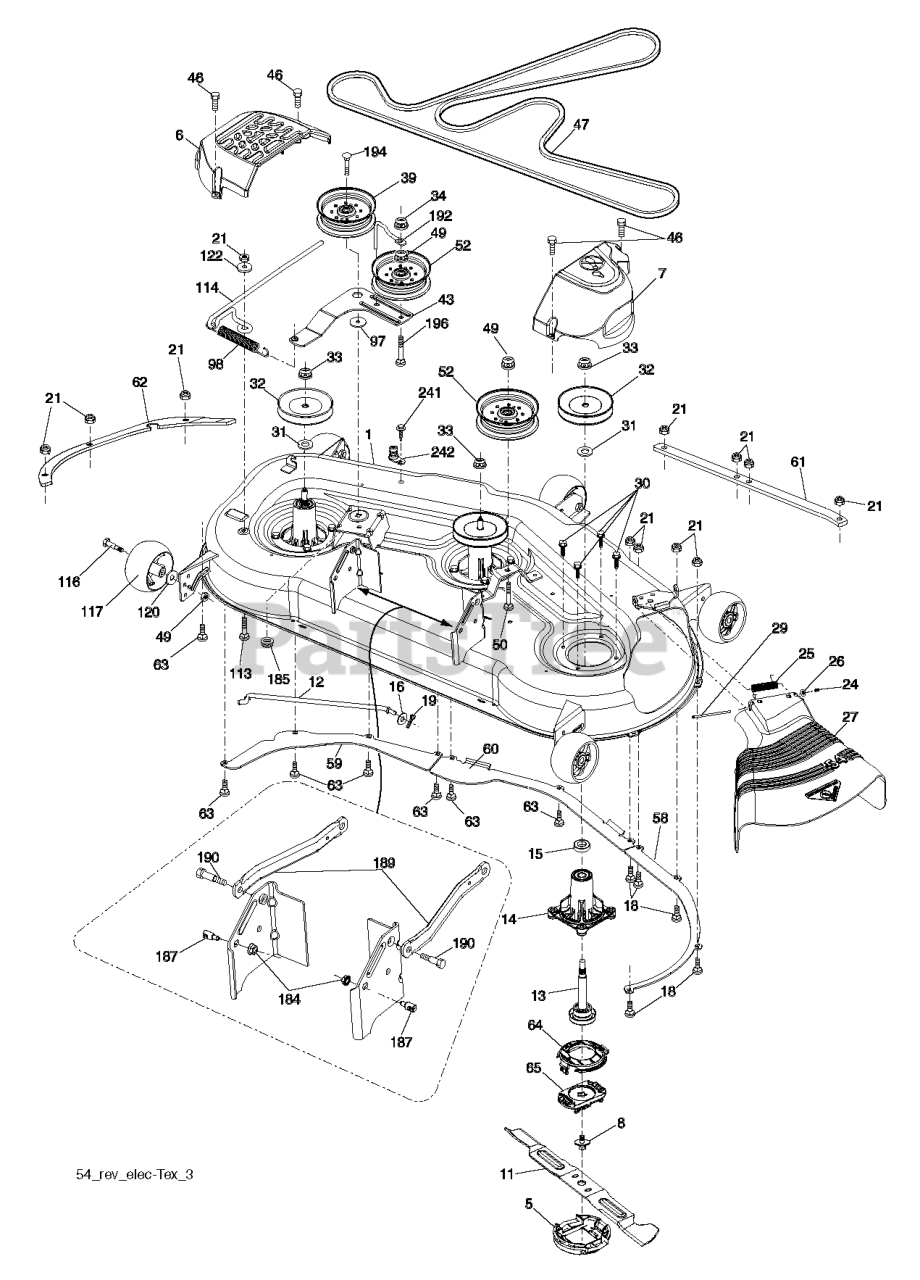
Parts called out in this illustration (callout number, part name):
1	DECK.WLDMT.W/TUBES.54".ORANGE
5	HOLDER BLADE REVOLUTION
6	COVER.MANDREL.LH.54"20
7	COVER.MANDREL.RH.54.20
8	SCREW.SEMS.7/16-20X1.HEX.HEAD
11	BLADE.BAGGER.54"
12	ROD.ANTI.SWAY.48/54"TE
13	MANDREL.ASM.REV.TALL.N/GRSABLE
14	RP.HOUSING.MANDREL.4PT.
16	WASHER
18	BOLT
19	PIN.COTTER.5/16.BOW TI
21	LOCKNUT
24	CAP-SLEEVE LT
25	SPRING, TORSION
26	NUT PUSH M
27	DEFLECTOR
29	ROD.HINGE
30	BOLT.HEX.WASHR.HED.313-18X1.19
31	WASHER.SPACER.MANDREL
32	PULLEY/MANDREL
33	NUT.FLANGE.LOCK.TOP
39	RB PULLEY.IDLER.4.50/HUB SPEC
43	ARM.IDLER
46	SCREW.1/4-20X5/8
47	RP.BELT.DRIVE.54."2006
49	NUT LOCK FLG 3/8-16 UNC
50	BOLT
52	PULLEY.IDLER.2006
58	BAFFLE.RIGHT.54"
59	BAFFLE.LEFT.54"
60	BAFFLE CENTER 54" MOWER
61	PLATE.REIN.FRONT.BOLT54"X431
62	PLATE.REIN.SIDE.BOLT.54"X431
63	BOLT.CARRIAGE.5/16-18
64	CAP.REVOLUTION.UPPER
65	CAP.REVOLUTION.LOWER
98	SPRING, DECK DRIVE
113	BOLT CRT
114	ROD TENSION RELIEF
116	BOLT.SHOULDER.3/8-16X3-5/8.
117	RP WHEEL. GUAGE RALLY
120	WASHER
122	BUSHING.RELIEF.TENSION
184	NUT LOCK HEX FLANGE 5/16-18
185	NUT.LOCK.FLANGE.7/16
187	STUD.FASTNER.W/ANTI-ROTATE
189	ARM.SUSPENSION.MOWER
190	BOLT.SHOULDER
192	KEEPER.BELT.IDLER.54"T
194	BOLT.HEX.WASHER.HEAD.7/16-24X
196	BOLT
241	SCREW.TT.#10-32X.5.3/8.FLANGE
242	PORT.WASHOUT
